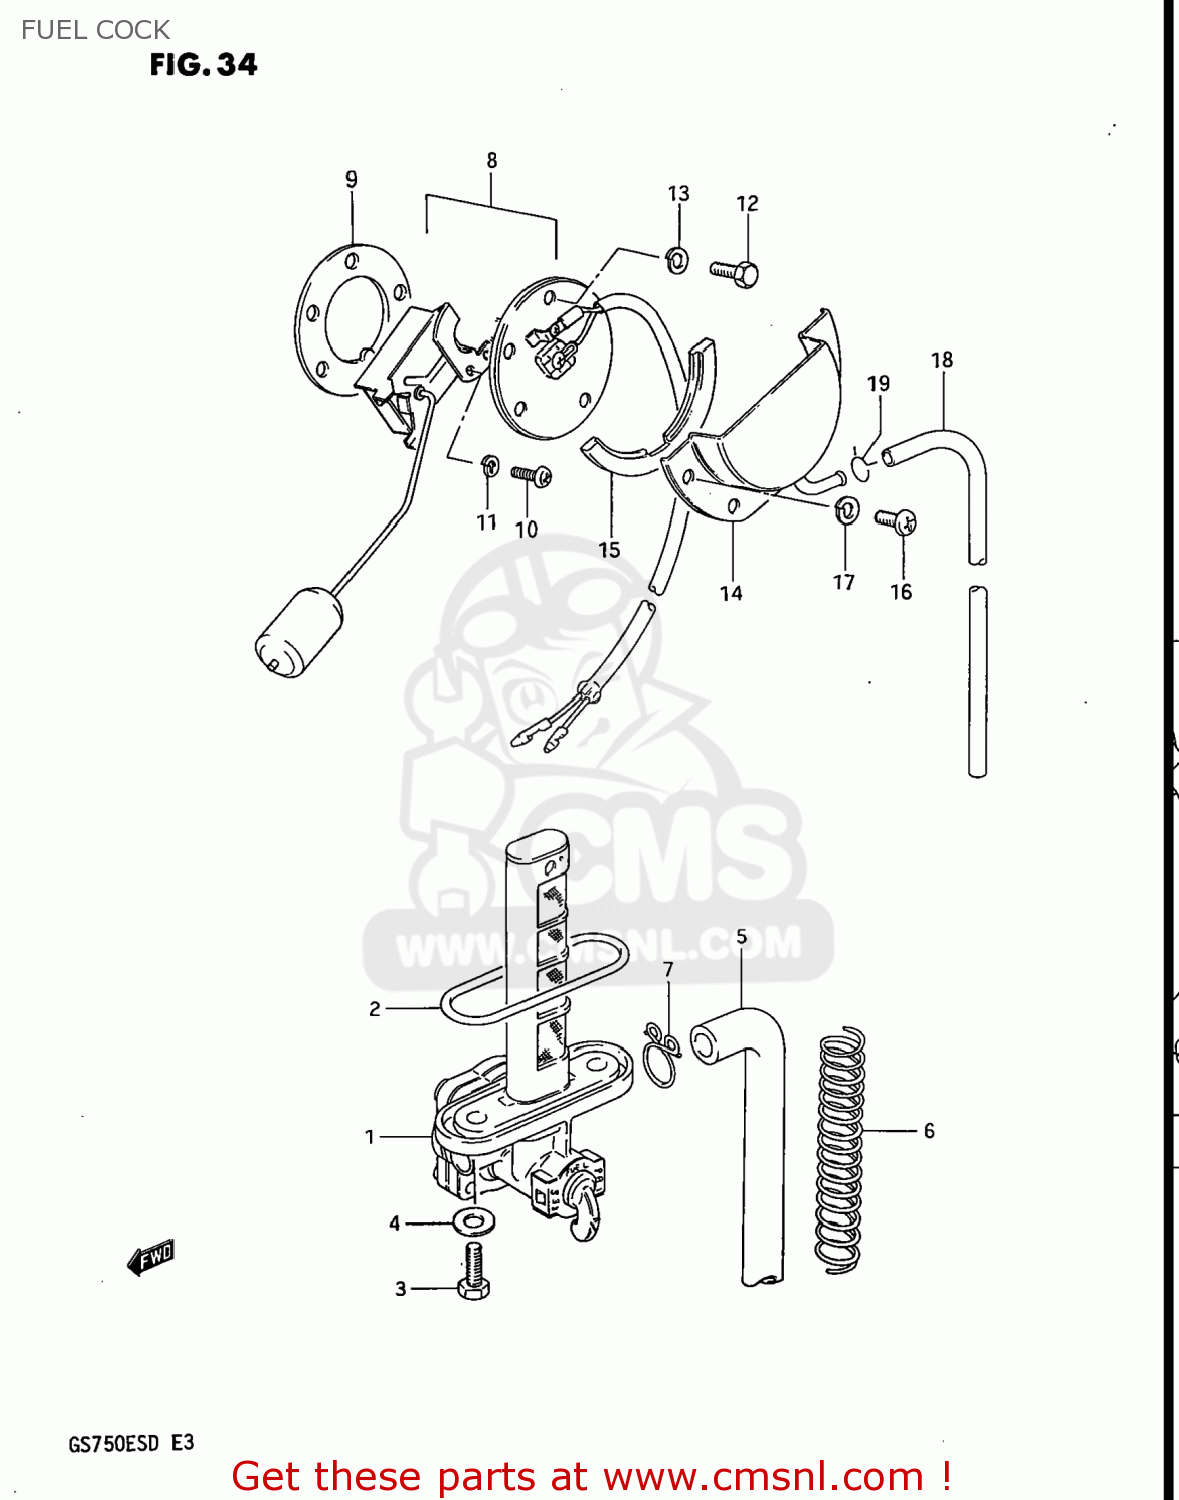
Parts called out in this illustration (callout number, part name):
1	COCK ASSEMBLY,FUEL
2	O RING
3	BOLT(6X20)
4	GASKET
5	HOSE
6	SPRING
7	CLIP
8	GAUGE ASSEMBLY,FUEL LEVEL
9	GASKET,FUEL LEVEL GAUGE (NAS)
10	SCREW
11	LOCK WASHER
12	BOLT
13	LOCK WASHER
14	PLATE,FUEL DRAIN
15	GASKET (NAS)
16	SCREW
17	LOCK WASHER
18	HOSE,FUEL
19	CLIP
